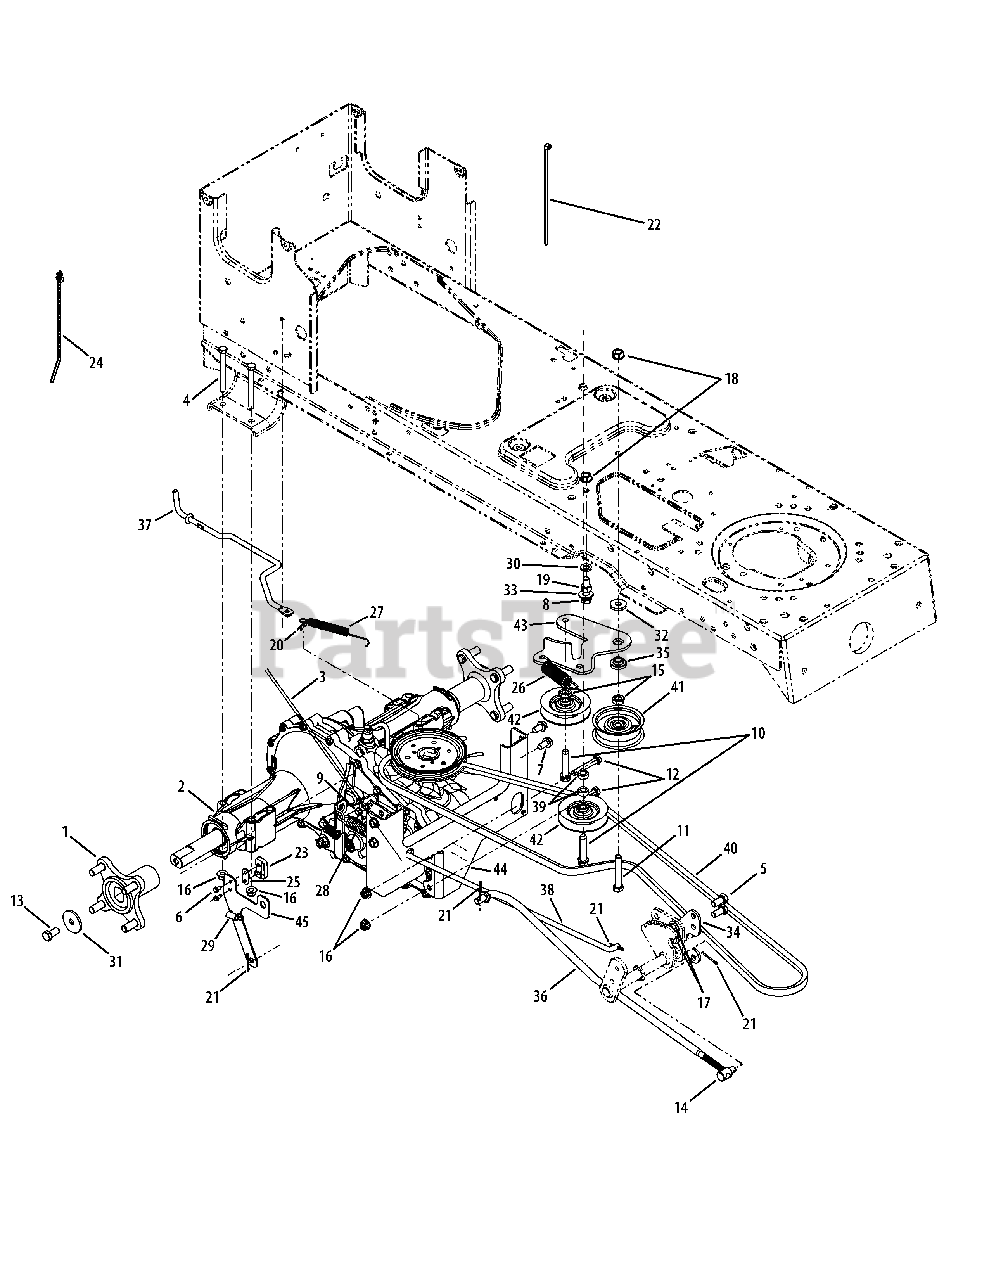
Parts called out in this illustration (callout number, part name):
1	Hub Assembly
2	Transmission, Hydrostatic
3	Wire Harness, Reverse
4	Screw, Hex Cap, 5/16-18 x 3.00 Gr5
5	Screw, Hex Cap, 3/8-16 x .75 Gr5
6	Screw, Hex Wash Hd Tapp, #8-18 x .5
7	Screw, Hex Cap, 5/16-18 x .750
8	Screw, Hex Cap, 3/8-16 x 1.50 Gr5
9	Screw, Self-Tapp, 1/4-20 x .5
10	Sems Screw, 3/8-16 x 1.875
11	Hex Cap Screw, 3/8-16 x 2.25, Gr5
12	Screw, Hex Cap, 5/16-18 x 2.00
13	Screw, Hex Cap Lock, 3/8-16 x .75
14	Ferrule, 3/8-24 x .375 Dia
15	Jam Nut, 7/16-20
16	Nut, Flange Insert Lock, 5/16-18 Gr5
17	Nut, Flange Insert Lock, 3/8-16 GrF
18	Nut, Flange Insert Lock, 3/8-16 GrF
19	Nut, Hex, 3/8-16, GR5
20	Pin, Cotter, .072 Dia. x 1.13
21	Pin, Cotter, 3/32, 1.0
22	Cable, Tie, 3/16 x .05 x 7.4
23	Switch, Spring, Short
24	Tie, Cable, Push Mount 7.5
25	Plate, Insulator Nut
26	Spring, Extension, .77 Dia x 3.7 Lg
27	Spring, Extension, .50 OD x 5.00 Lg
28	Spring, Extension, .59 OD x 4.00 Lg
29	Spring, Extension, 3/8 OD x 1.44 Lg
30	Washer, Lock, 3/8 , Regular Duty
31	Washer, Flat, .390 x 1.50 x .134
32	Washer, Flat, .385 x 1.0 x .135
33	Washer, Flat, .406 x .875 x .059
34	Bracket, Speed Control
35	Spacer, Shoulder, 1.00 x .38 x .38
36	Rod, Hydro Control
37	Rod, Hydro Disengage
38	Rod, Brake
39	Spacer, .380 x .625 x .265
40	Belt, V-Type
41	Pulley, Idler, Flat 2.75 OD
42	Pulley, Idler, Flat 3.06 OD
43	Bracket, Idler
44	Bracket, Torque
45	Bracket, Actuator
